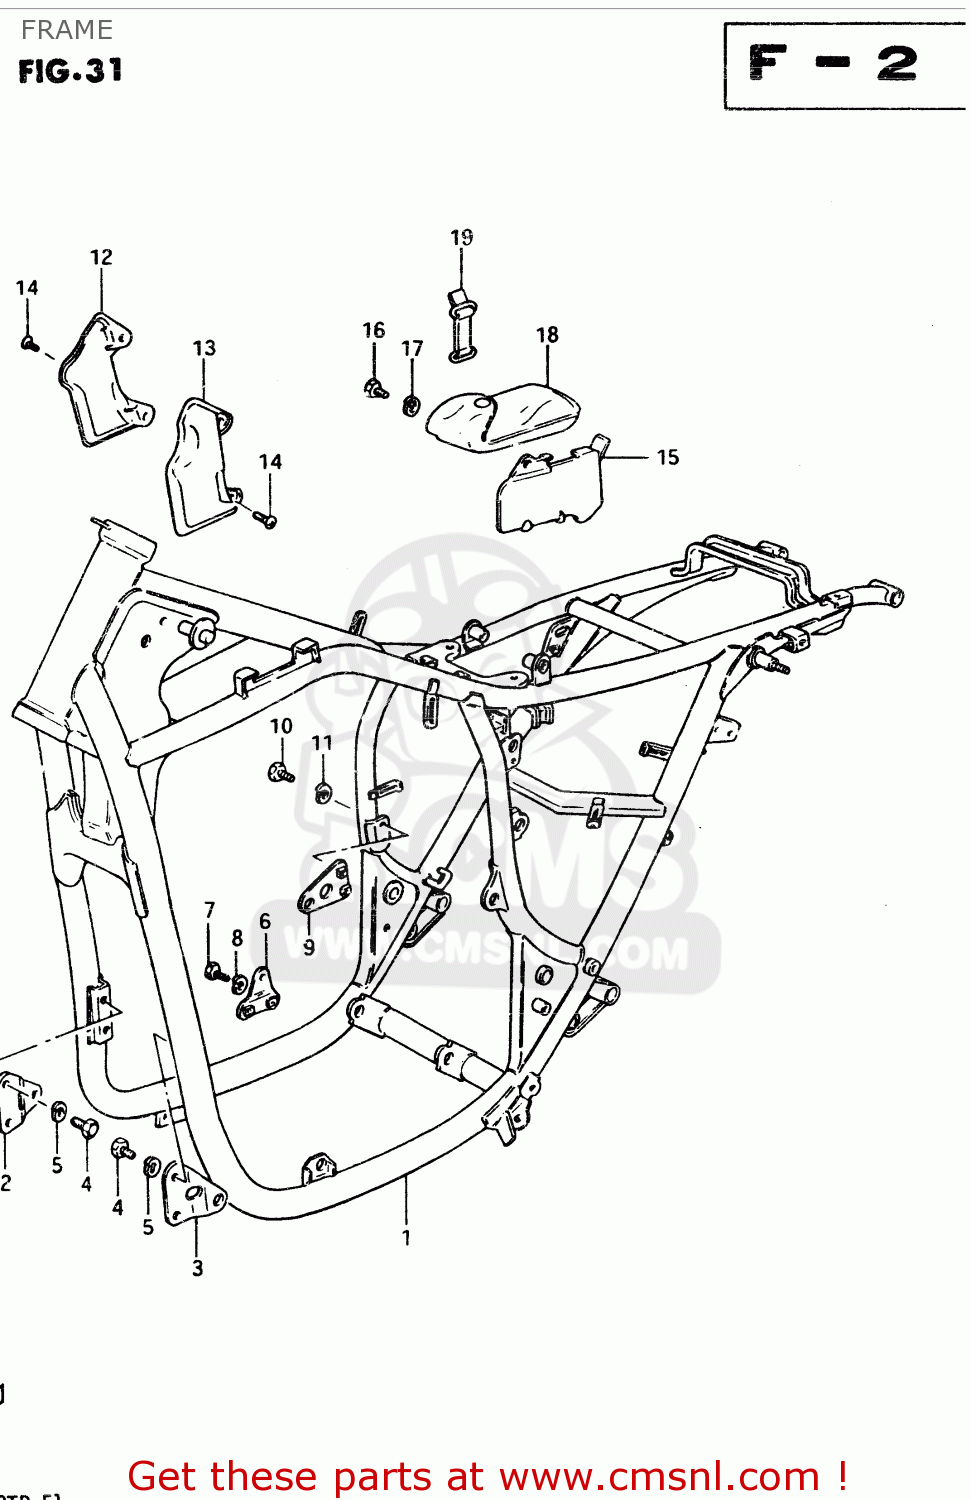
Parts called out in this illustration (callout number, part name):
1	FRAME (BLACK)
2	PLATE,ENG MTG NO.1,R
3	PLATE,ENGINE MOUNTING,LEFT
4	BOLT
5	LOCK WASHER
6	PLATE,MOUNTING NO.2,LEFT
7	BOLT
8	LOCK WASHER
9	PLATE,MOUNTING NO.4,LEFT
10	BOLT 8X45
11	LOCK WASHER
12	COVER,FRAME HEAD,RIGHT
13	COVER,FRAME HEAD,LEFT
14	SCREW M5X12 DIN 7985/N
15	HOLDER,TOOL
16	BOLT
17	LOCK WASHER
18	TOOL SET
19	BAND
